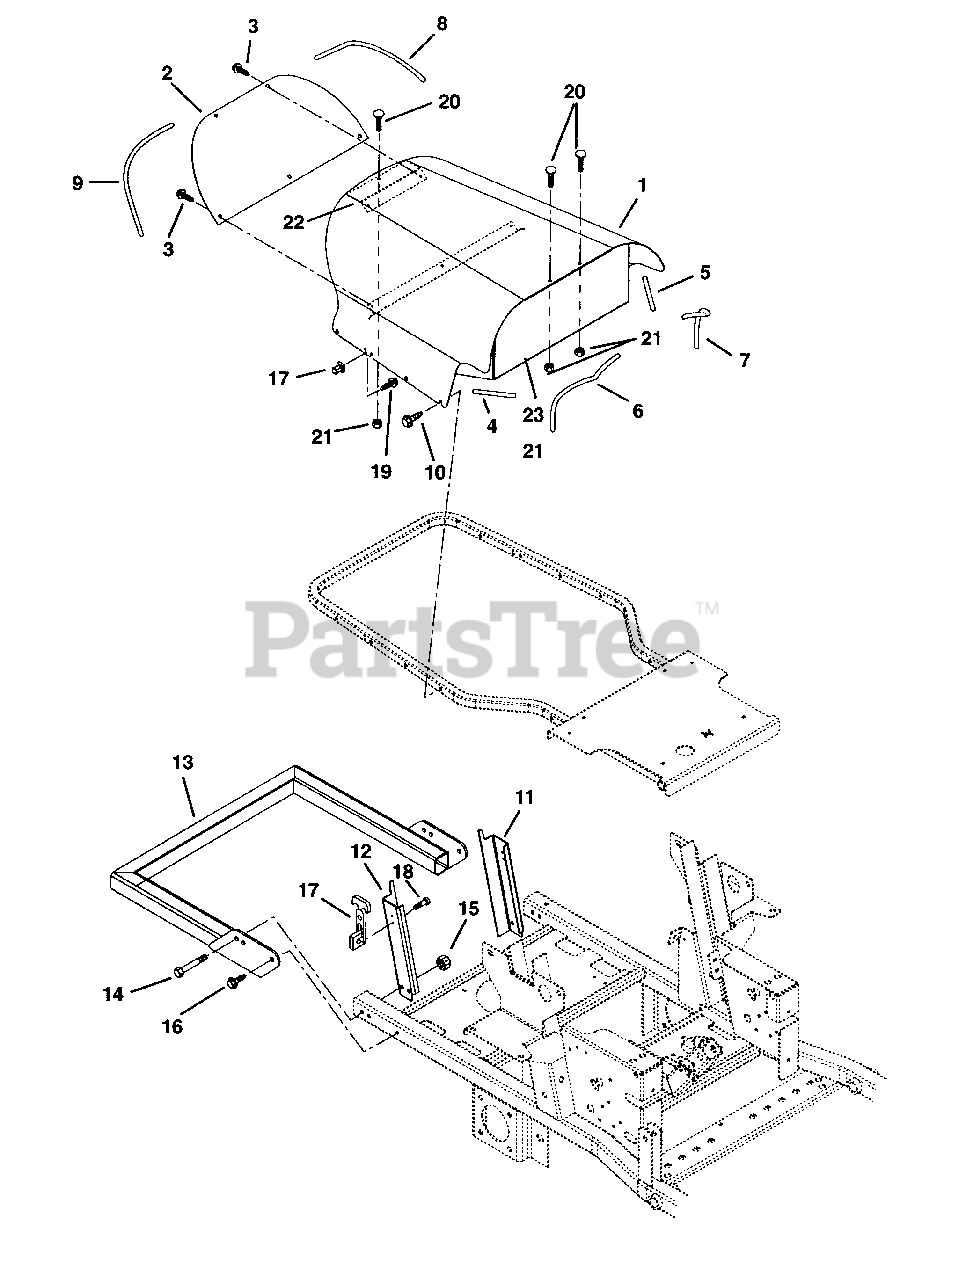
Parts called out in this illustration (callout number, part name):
1	Hood
2	Screen-Hood
3	Screw-Tapping .25-20 x .50 Hex Washer Head
4	Seal-Trim-Lok Bulk .06 Bubble
5	Seal-Trim-Lok Bulk .06 Bubble
6	Seal-Trim-Lok Bulk .06 Bubble
7	Seal-Trim-Lok Bulk .06 Bubble
8	Seal-Trim-Lok Bulk .06 Bubble
9	Seal-Trim-Lok Bulk .06 Bubble
10	Screw-Tapping .38-16 x .50 Hex Washer Head
11	Hood Support Left-Hand
12	Hood Support Right-Hand
13	Bumper-Rear
14	Bolt-Hex .38-16 x 3.00 Grade 5
14	Bolt-Hex .38-16 x 2.50 Grade 5
15	Nut-Locking-Center .38-16
16	Screw-Tapping .38-16 x .75 Hex Washer Head
17	Latch-Rubber
18	Screw-Machine 10-24 x .50 Hex Washer Head
19	Screw Machine 10-24 x .50 Hex Washer Head
20	Bolt-Round Head Square Shank .25-20 x .50 Grade 5
21	Nut-Locking-Nylon .25-20
22	Bracket-Screen Support
23	Weldment, Plenum
